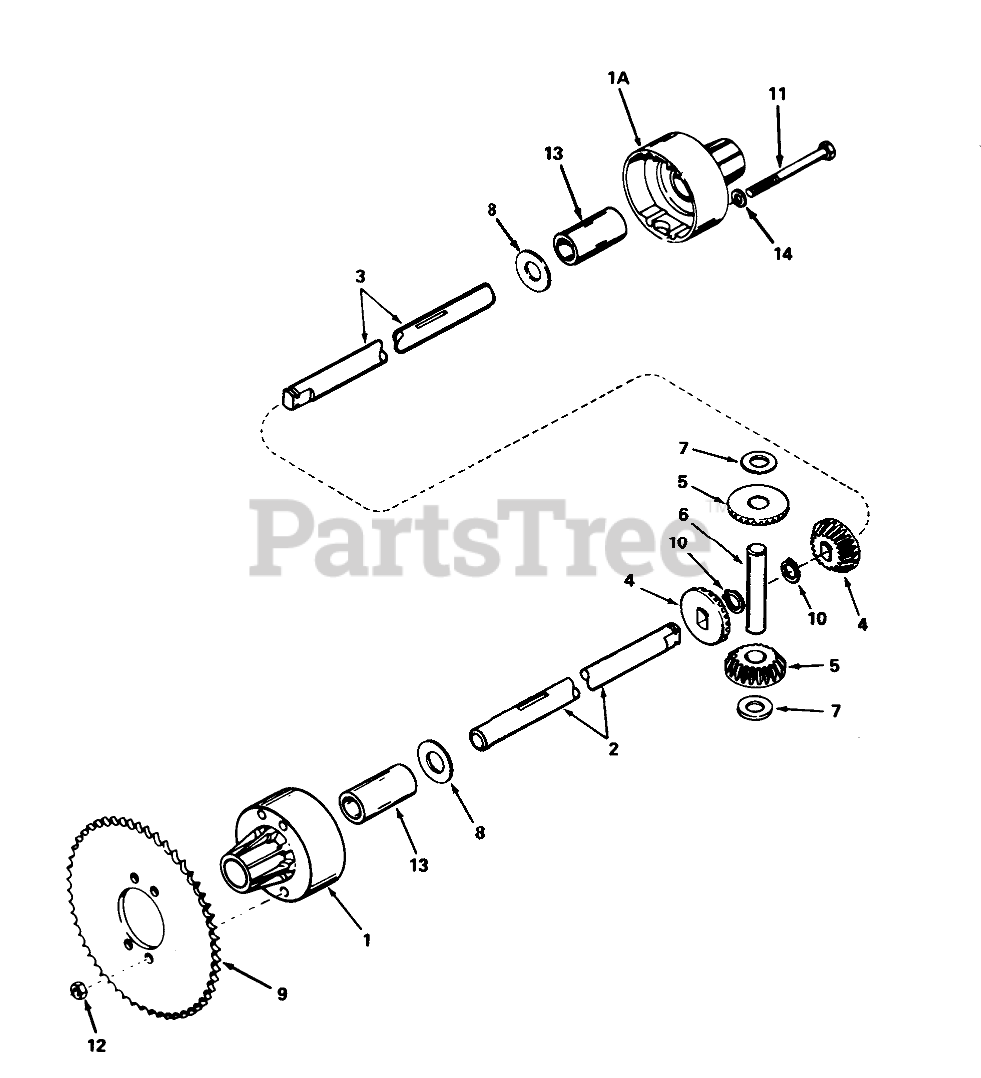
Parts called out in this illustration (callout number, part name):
1	Housing-Differential Carrier (Incl. #13)
1A	Housing-Differential Carrier (Incl. #13)
2	Axle (9-5/8" long)
3	Axle (18-1/4" long)
4	Bevel Gear
5	Gear Pinion
6	Pin Drive
7	Washer Thrust
8	Washer
10	Ring-Snap
11	Screw-Hex Hd.
12	Nut-Lock
13	Bushing
14	Washer
